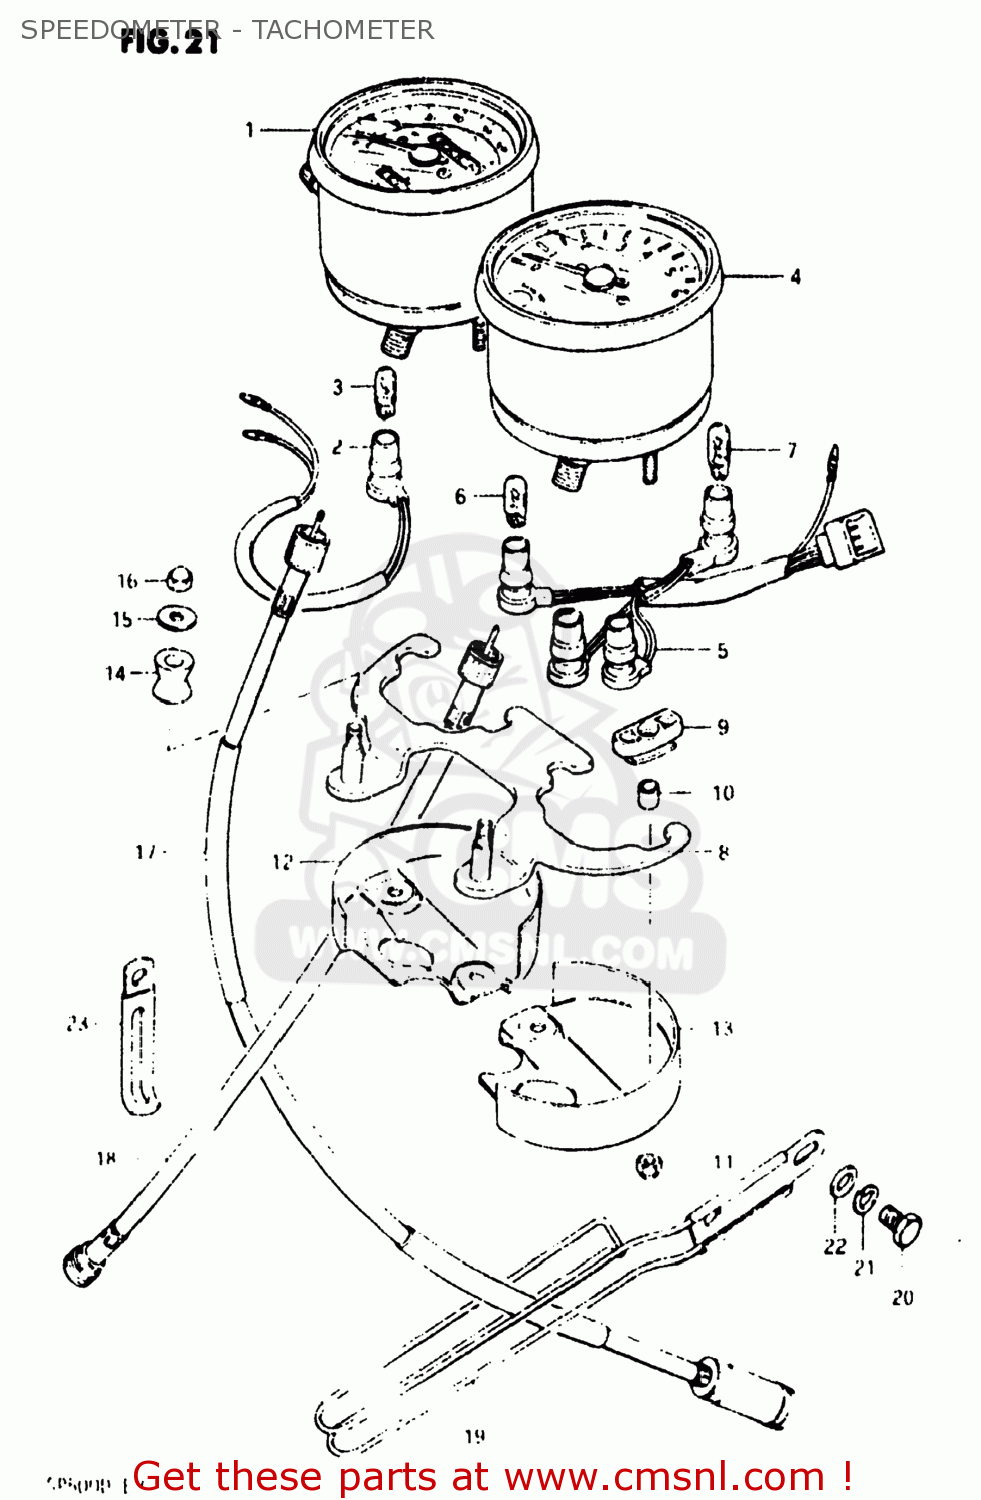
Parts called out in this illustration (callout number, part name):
1	METER,SPEEDOMETER
2	SOCKET,METER
3	BULB(6V,3W)
4	TACHOMETER
5	SOCKET,TACHOMETER
6	BULB(6V1.7W,STANLEY,A61A)
7	BULB(6V,3W)
8	BRACKET,COMBINATION METER
9	CUSHION
10	SPACER
11	NUT
12	COVER,METER,UNDER
13	PLATE,TACHOMETER UNDER
14	CUSHION
15	WASHER
16	NUT
17	CABLE ASSY,SPEEDOMETER
18	CABLE ASSY,TACHOMETER
19	GUIDE,CABLE
20	BOLT 8X12
21	LOCK WASHER
22	WASHER
23	CLAMP L:35
